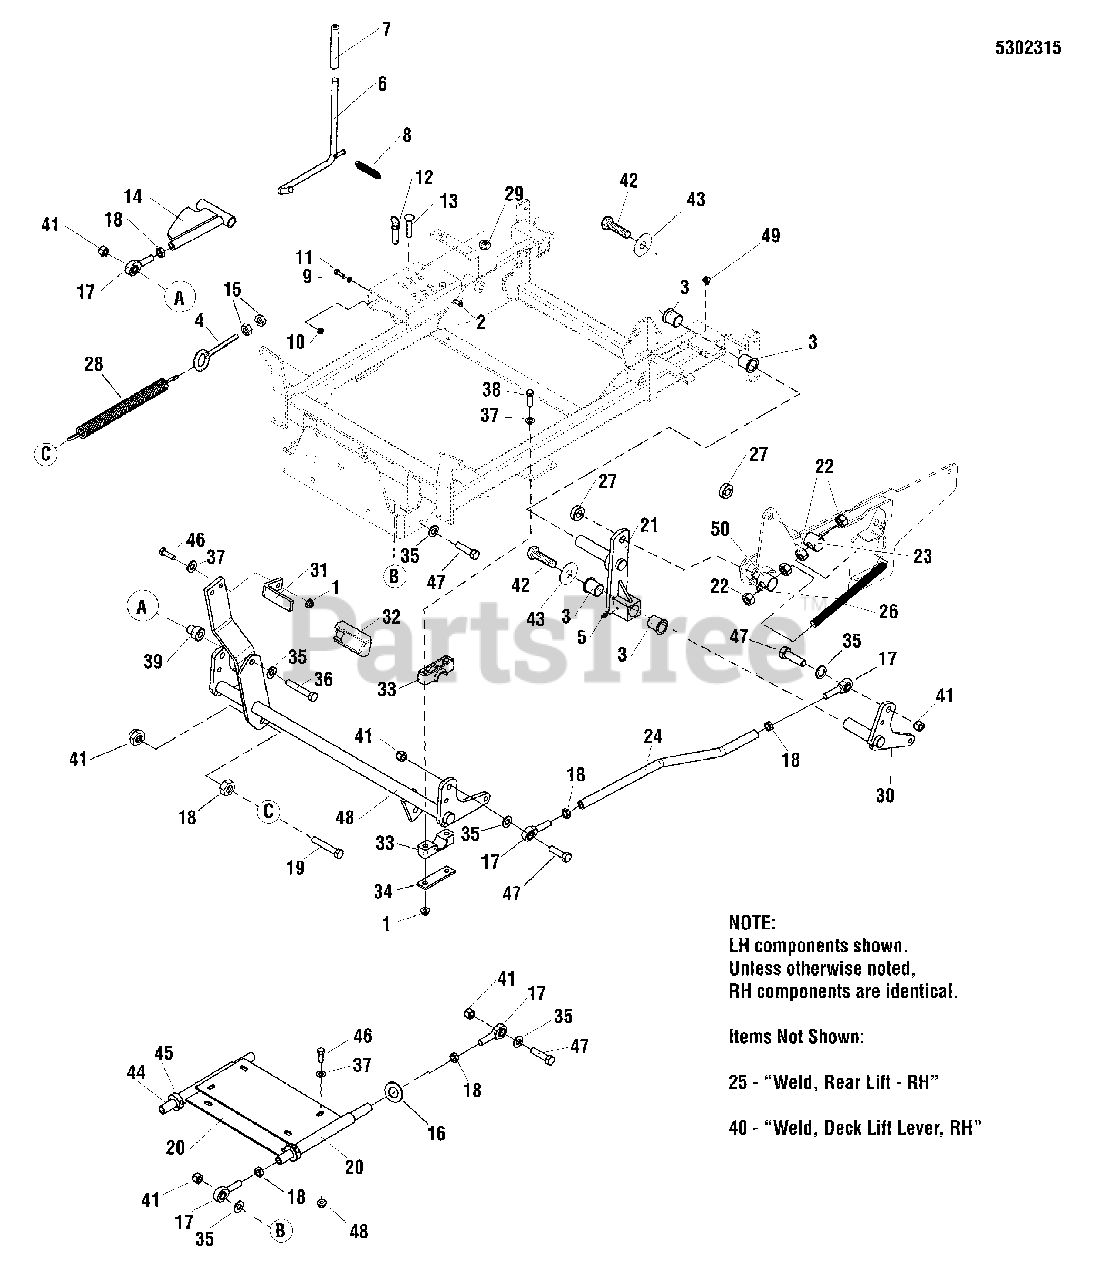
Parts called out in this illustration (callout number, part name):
1	NUT, 3/8-16 HEX NYLOCK FLANGE
2	CLEVIS PIN, 1/4 X 1/2, YZ
3	BUSHING, 1.00 X 1.13 X 1.38, PLASTIC
4	EYE BOLT, 3/8-16 X 6, 3.0 THRD, 1 EYE
5	GREASE FITTING, 1/4-28 STRAIGHT
6	WELD, ROD DECK LIFT - BLK
7	GRIP, FOAM
8	SPRING, EXTENSION
9	WASHER, 1/4 SAE (5025154)
10	NUT, 1/4-20 HEX SERR. FLANGE
11	BOLT, 1/4-20 X 3/4 GD5 YZ
12	PIN, HITCH, 1/2 X 2.00 OAL, YP
13	BOLT, 3/8-16 X 2, CARRIAGE
14	WELD, DECK ADJUST LINK
15	NUT, 3/8-16 HEX
16	WASHER, 1/2 SAE
17	BALL JOINT, 1/2-20, MALE
18	NUT, 1/2-20 HEX JAM
19	BOLT, 1/2-13 X 2-1/4 GD5 YZ
20	WELD, DECK STABILIZER - BLK
21	WELD, REAR LIFT, LH - BLK
22	NUT, 5/8-11 HEX
23	PIVOT, SPRING ROD
24	ROD, DECK LIFT BENT
25	WELD, REAR LIFT, RH - BLK
26	ROD, 5/8-11 X 9.00
27	COLLAR, 5/8 SPLIT
28	SPRING, DECK LIFT ASSIST
29	NUT, 3/8-16 HEX SIDE LOCK
30	WELD, DECK LIFT LEVER, LH - BLK
31	PEDAL, FOOT - BLK
32	RUBBER, FOOT PEDAL
33	PIVOT BLOCK, PLASTIC
34	PLATE, PIVOT BLOCK SUPPORT - BLK
35	WASHER, 1/2 GD9 YZ
36	BOLT, 1/2-13 X 3-1/2 GD5
37	WASHER, 3/8 SAE
38	BOLT, 3/8-16 X 2-3/4 GD5 YZ
39	ADAPTER, CASTER AXLE
40	WELD, DECK LIFT LEVER, RH - BLK
41	NUT, 1/2-20 HEX NYLON LOCK
42	BOLT, 3/8-16 X 3/4, GD5, YZ WITH PATCH
43	WASHER, .390 X 1.50 X .109, YZ
44	SHAFT, DECK STABILIZER
45	COLLAR, 3/4 SPLIT
46	BOLT, 3/8-16 X 1 GD5 YZ
47	BOLT-1/2-20 X 1-3/4 GD5 YZ
48	WELD, DECK LIFT SHAFT
49	GREASE FITTING, 1/4-28, 90 DEGREE
50	PIVOT, SPRING ROD
